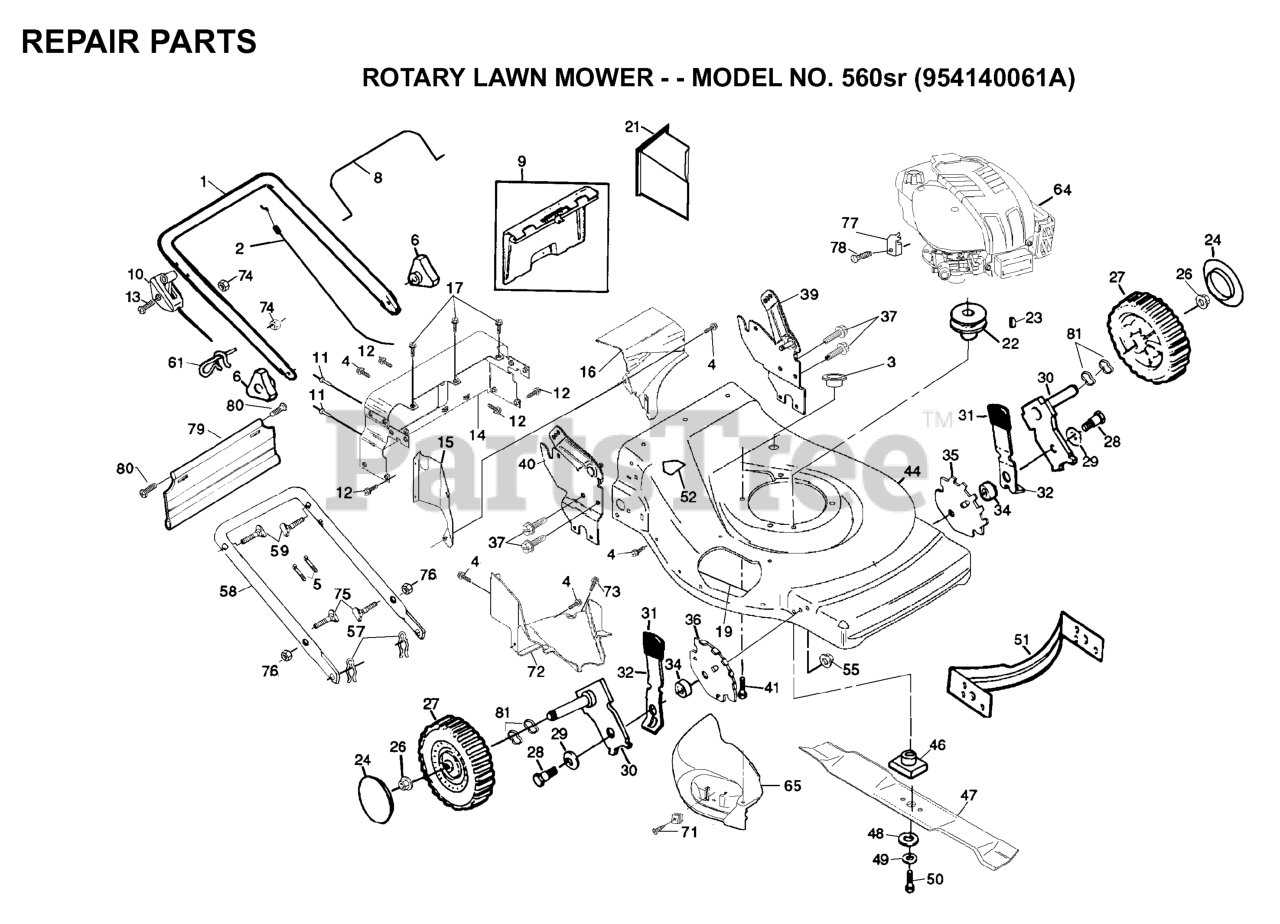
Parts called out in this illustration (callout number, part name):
2	CABLE-ZONE
4	SCREW.HXTAP.10-24
5	TIE GUIDE
8	CONTROL BAR
10	THROTTLE CONTROL
11	RIVET BLIND
13	SCREW 1/4-20X1.75
15	SIDE BAFFLE
16	DISCHARGE BAFFLE
21	MULCHER PLUG
22	ENGINE.PULLEY.FWG
23	HI PRO KEY PM WSL
24	HUBCAP.8".GREY
26	HEX FLANGE LOCKNT
27	WHEEL.8X2.PR.LP.RAD.GREY
28	BOLT
29	WASHER.BELLEVILLE (3 2 LB)
30	AXLE ARM
31	SELECTOR KNOB
32	SELECTOR SPRING
34	RP SPACER HT ADJ
35	WHL ADJ BRKT LF/RR
36	WHL ADJ BRKT RF/LR
37	SELF-TAPPING SCREW 5/16-18X3/4
41	BOLT 3/8-16X1-1/8
46	BLADE ADAPTOR
47	%BLADE, MULCH
48	WASHER,HARDEN
49	LOCKWASHER
50	SCREW, HEX HD 3/8-24 X 1-3/8
51	BAFFLE
52	DECAL HYT
55	LOCKNUT PM
57	HAIRPIN COTTER
59	HANDLE BOLT
61	ROPE GUIDE
71	SCREW.PAN.HEAD.#10
72	BAFFLE BELT COVER
73	SCREW.HX.13X.750
74	NUT
76	NUT
77	CABLE CLAMP(ENGINE)
78	SCREW.HEX.HEAD.WASHER.10-16
79	REAR SKIRT
80	HINGE SCREW
81	WAVE WASHER
